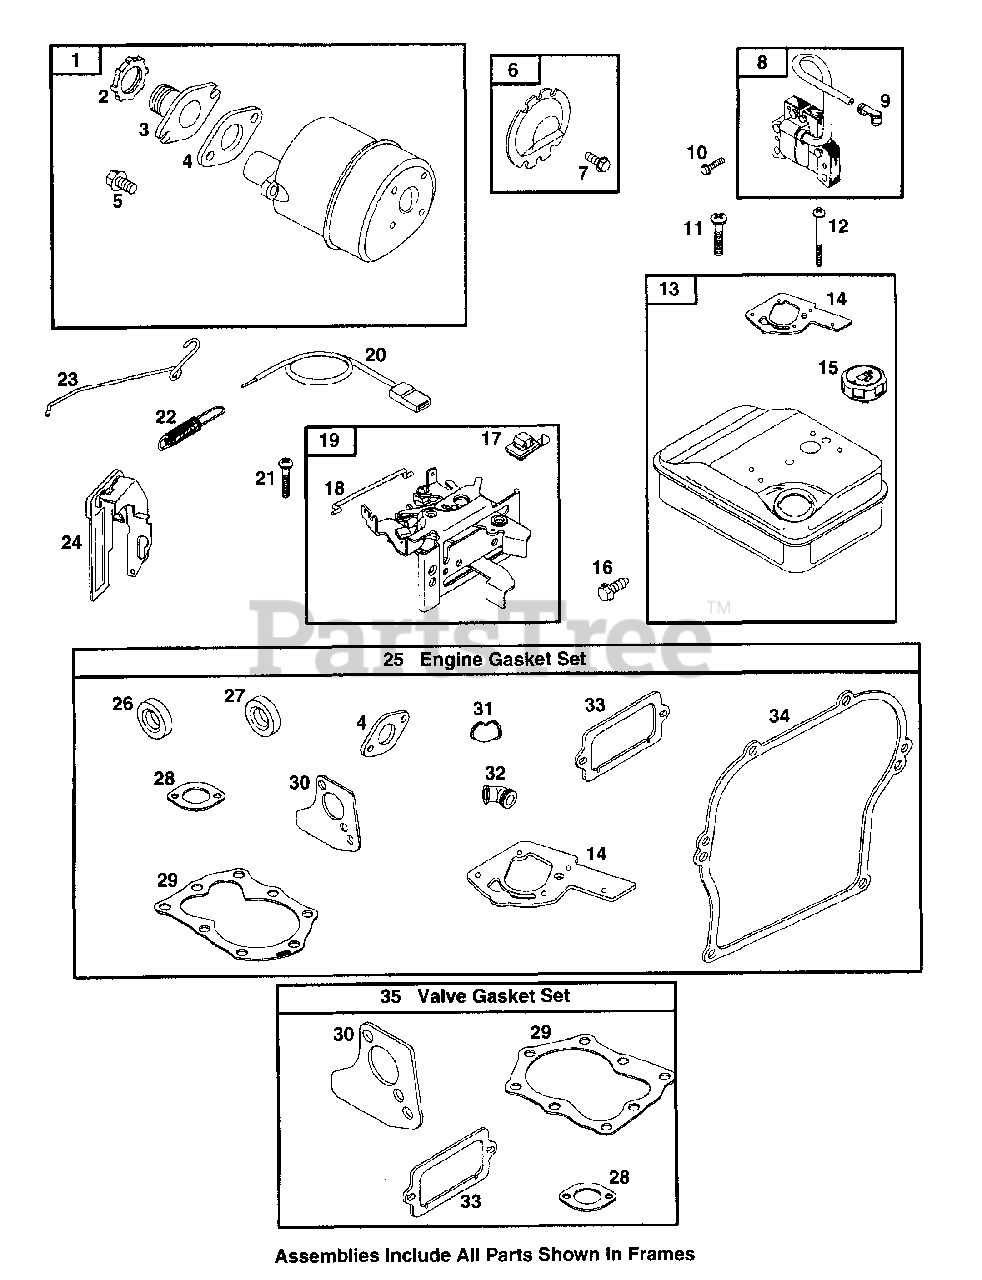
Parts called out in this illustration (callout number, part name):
1	Muffler-Exhaust
2	Muffler/Elbow Locknut
3	Muffler Adapter
4	Exhaust Gasket
5	Screw (Muffler Adapter)
6	Muffler Deflector
7	Screw (Muffler Deflector)
8	Armature-Magneto
9	Sparkplug Terminal
10	Screw (Magneto Armature)
11	Screw, 3/4" Long (Carburetor)
12	Screw, 1 3/4" Long (Carburetor)
14	Fuel Tank Gasket
15	Fuel Tank Cap
16	Screw (Fuel Tank)
17	Switch-Stop
18	Choke Link
19	Speed Control Panel
21	Screw (Speed Control Panel)
22	Governor Spring
23	Link-Air Vane
24	Governor Blade
25	Engine Gasket Set
26	Oil Seal
28	Air Cleaner Gasket
29	Cylinder Head Gasket
30	Intake Gasket
32	Grommet
33	Breather Gasket
